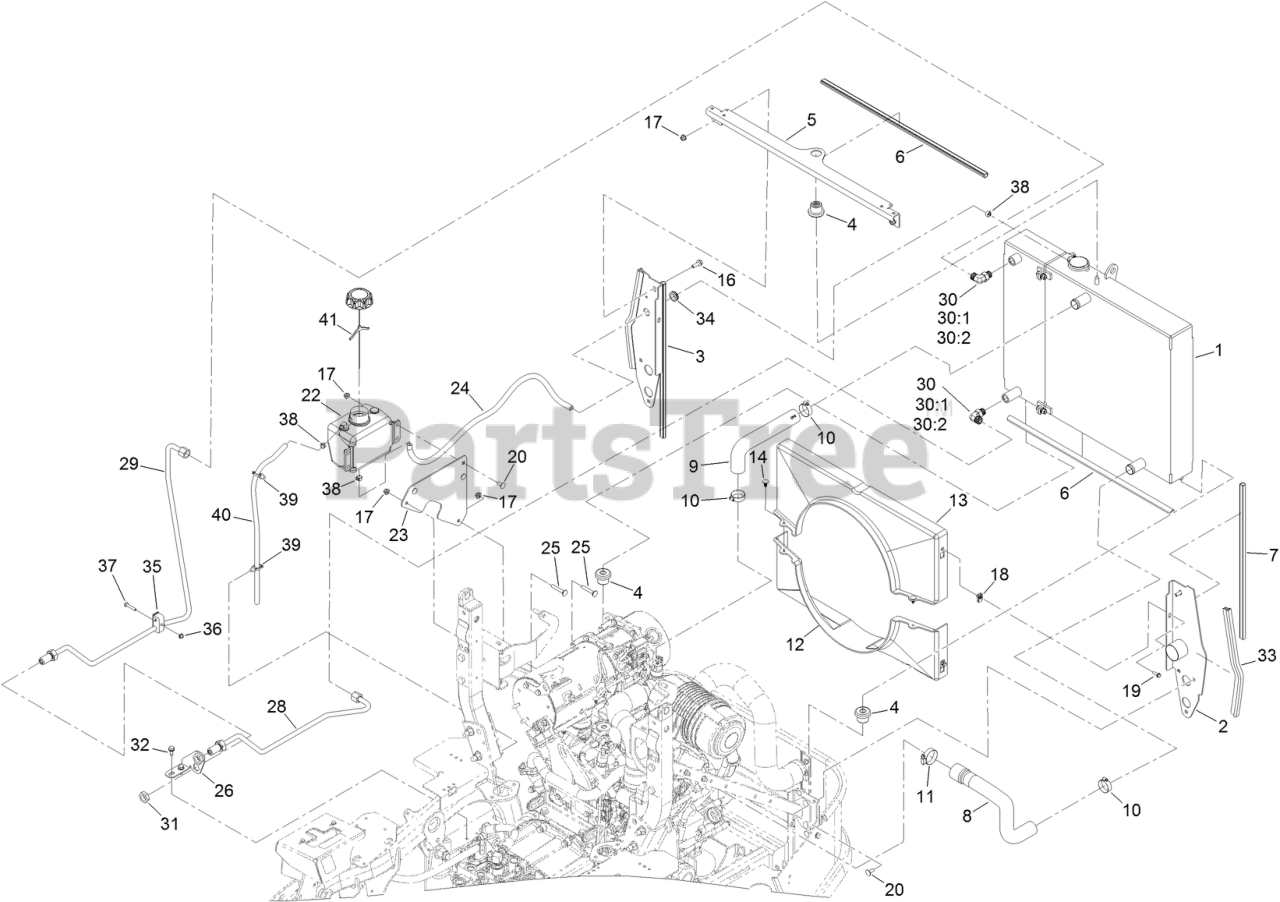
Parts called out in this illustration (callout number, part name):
1	COOLING ASM
2	SUPPORT-RADIATOR, LH
3	SUPPORT-RADIATOR, RH
4	MOUNT-ISOLATOR
5	BRACKET-COOLING, TOP
6	SEAL-BULB
7	SEAL-BULB
8	HOSE-RADIATOR, LOWER
9	HOSE-RADIATOR, UPPER
10	CLAMP-HOSE
11	CLAMP-HOSE
12	SHROUD-BOTTOM
13	SHROUD-TOP
14	PLUG-PLASTIC
16	SCREW-HHF
17	NUT-HF, NI
19	SCREW-HWH
20	SCREW-CARR
22	TANK-OVERFLOW, W/CAP
23	BRACKET-BOTTLE
24	HOSE-FUEL
25	BOLT-CARR
26	BRACKET-BULKHEAD
28	HYDRAULIC TUBE ASM
29	HYDRAULIC TUBE ASM
30	FITTING-ELBOW, 90 DEG
30:1	O-RING
30:2	O-RING
31	NUT-BULKHEAD
32	SCREW-HWHTF
33	SEAL-BULB
34	GROMMET
35	CLAMP-TWIN
36	NUT-HF
37	SCREW-HH
38	CLAMP-HOSE
39	CLIP-TIE
40	HOSE-FUEL
41	CAP-W/TETHER
